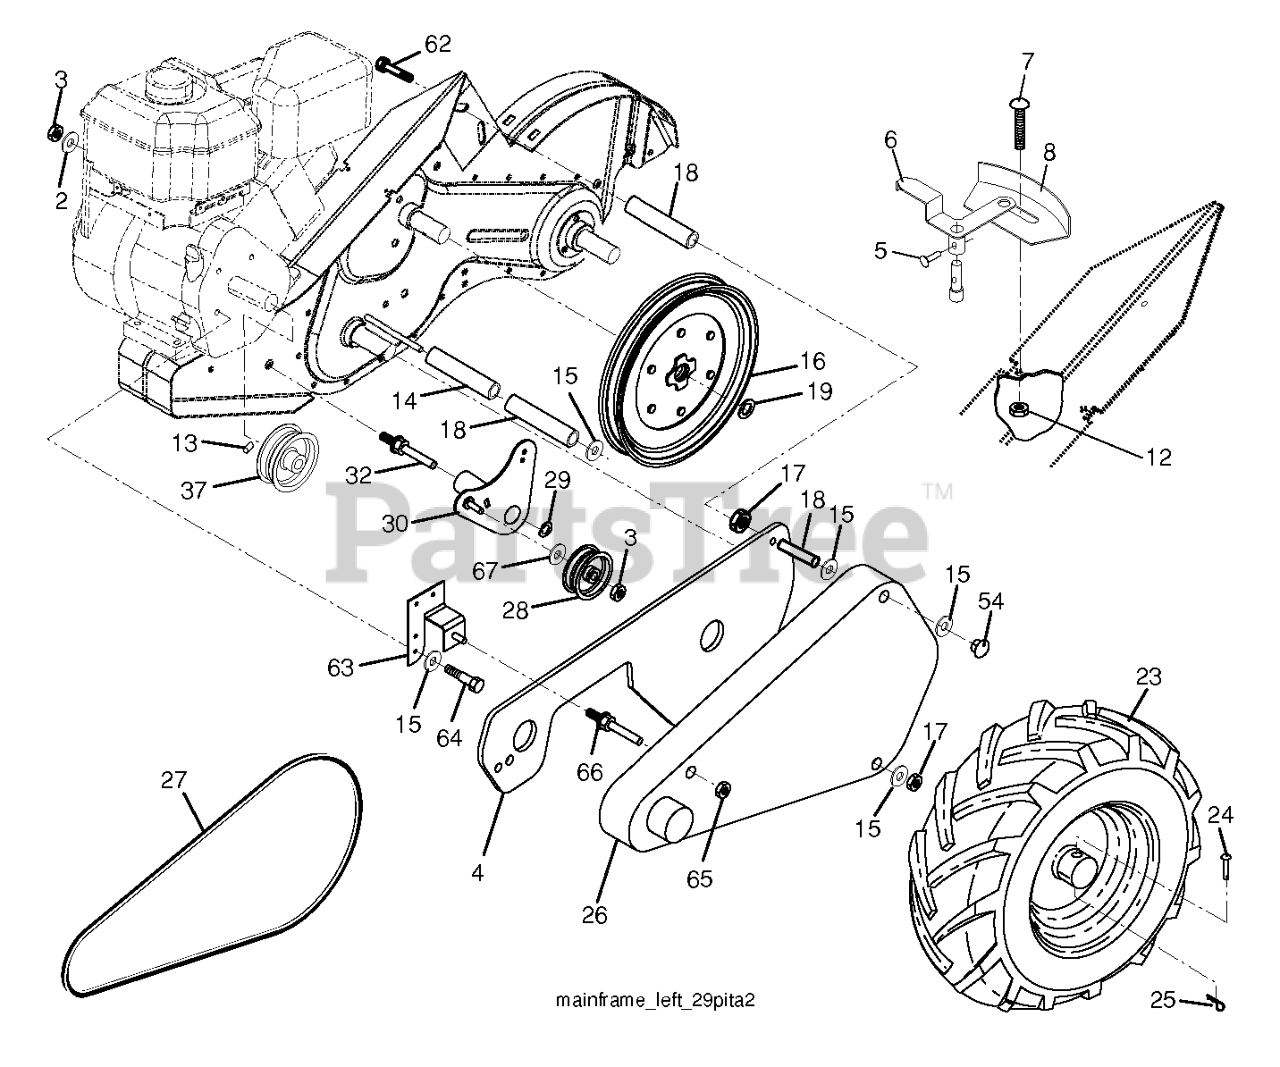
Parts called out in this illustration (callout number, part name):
2	WASHER, LOCK 3/8
3	LOCKNUT
5	PIN.SPIROL.FLARED
6	LEVER ASM CRT
8	PANEL.INDICATOR.SHIFT.BLACK
12	NUT
14	SPACER-SPLIT.327 X .42
15	WASHER
16	SHEAVE, TRANSMISSION
17	NUT
18	SPACER SPLIT
19	RETAINING RING LT
23	WHEEL.DR.LH.16X4X8.TILLER.SILV
25	SPRING TI
26	GUARD.BELT.TILLER.8HP.ORANGE
27	BELT, DRIVE
28	PULLEY-IDLER TI
30	BRACKET.IDLER.ASM.SHORT
32	SHAFT, IDLER ARM
37	RPSHEAVE.3.50.TILLER.ZINC.SUBA
62	BOLT 5/16-18X4 1/2
63	BRACKET.ASM.GRD.BELT.INTEK.PNT
66	GUIDE.BELT.REAR.TINE.TILLER.BL
67	WASHER
